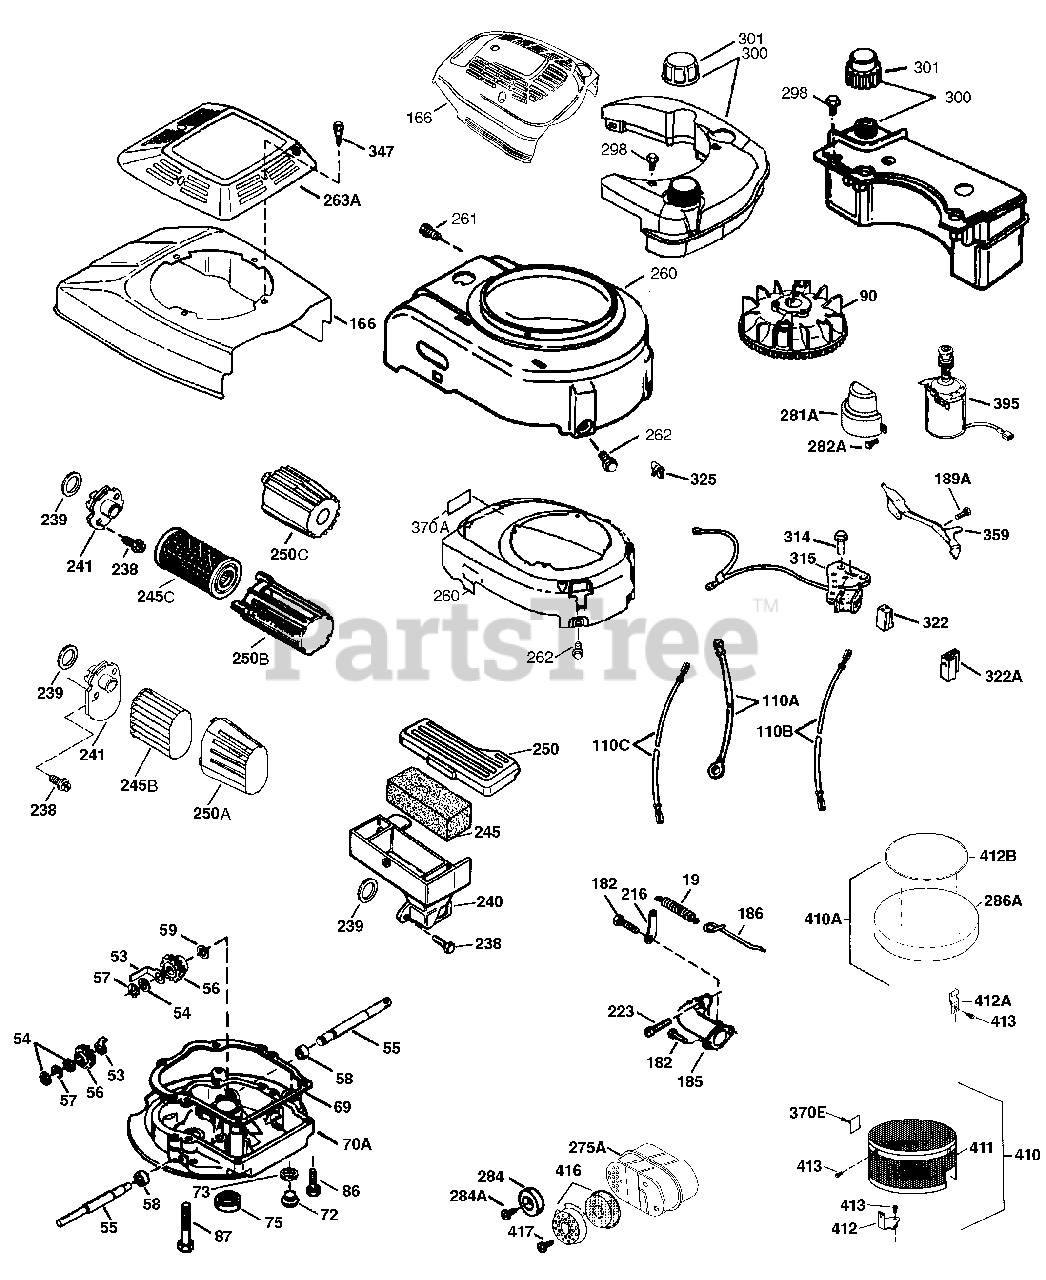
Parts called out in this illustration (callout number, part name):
19	Extension Spring
41	Piston & Pin Ass'y. (Std.) (Incl. 43)
41	Piston & Pin Ass'y. (.010" OS) Incl. 43
62	Screw, 8-32 x 3/8" (Optional)
65	Screw, 10-24 x 9/16"
69	* Mounting Flange Gasket
72	Oil Drain Plug (Flush Mount)
75	Oil Seal
86	Screw, 1/4-20 x 1-1/4"
90	Flywheel
110A	Ground Wire
130B	Screw, 1/4-20 x 1/2"
182	Screw, 1/4-28 x 7/8"
182	Screw, 1/4-20 x 1"
185	Intake Pipe
186	Governor Link
238	Screw, 10-32 x 49/64"
239	* Air Cleaner Gasket
241	Air Cleaner Collar
243	Screw, 10-32 x 7/16"
245B	Air Filter (Paper) (also available in Packaged Part #740083)
250A	Air Filter Cover
260	Blower Housing
262	Screw, 1/4-20 x 1/2"
275A	Spark Arrestor Muffler
300	Fuel Tank (Incl. 292 & 301)
301	Fuel Cap (Black)(1-1/2" I.D.) also av ailable in Packaged Part #740041B
416	Spark Arrestor Kit (Incl. 417) Option al
900	Replacement Engine None.
900	Replacement Short Block None.
999	Summer Maintenance Kit (incl. Oil, Sp ark Plug, Air Cleaner, & Ultra-Fresh)
